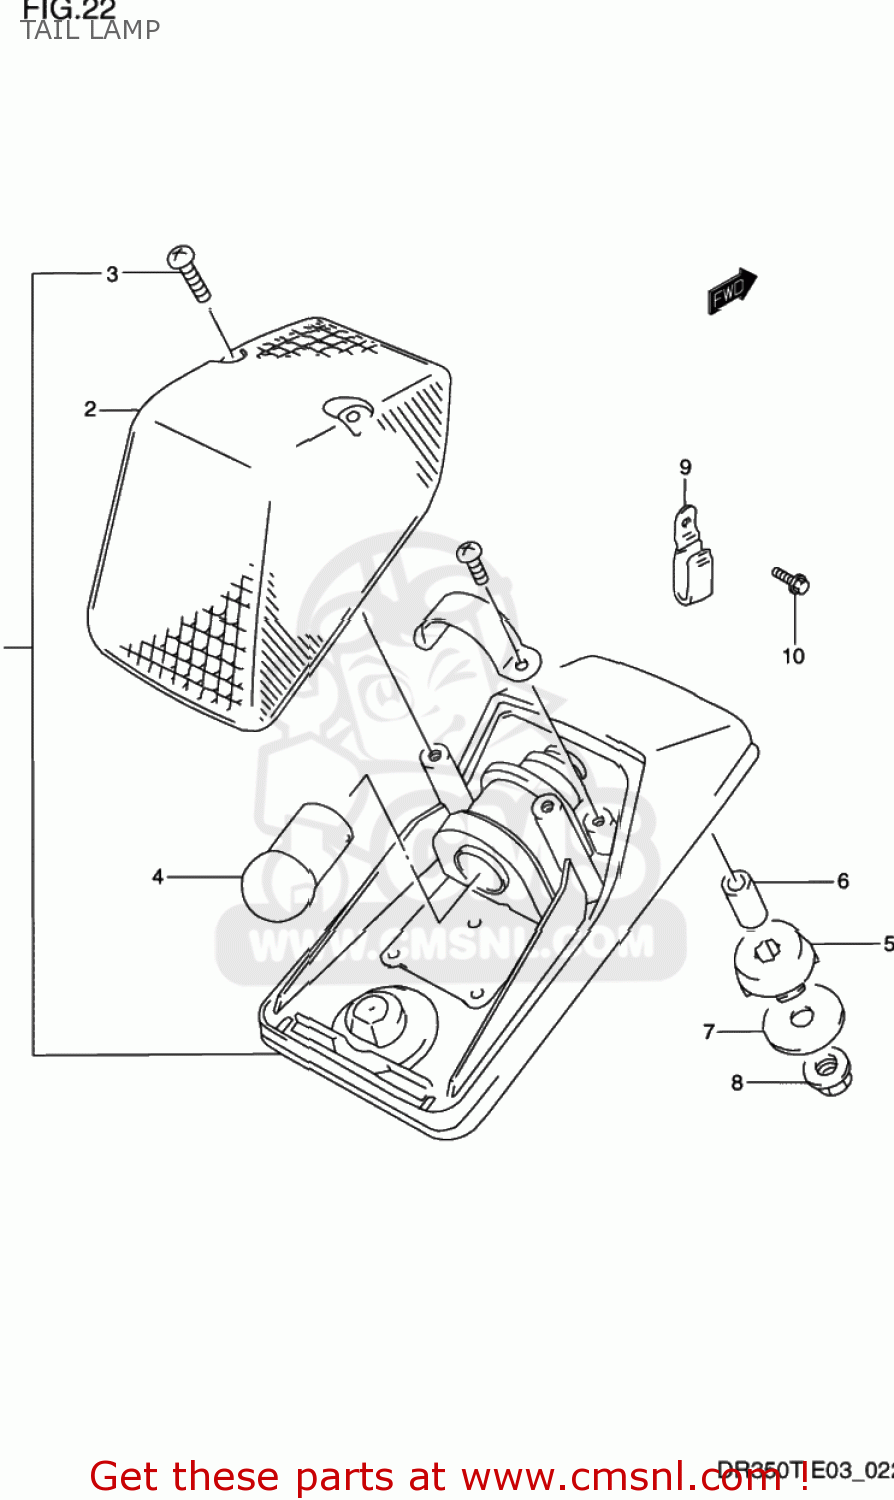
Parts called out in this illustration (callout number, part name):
1	LAMP ASSY,TAIL
2	LENS
3	SCREW
4	BULB(12V5W,BF150-40160A)
5	CUSHION
6	SPACER(6.4X9.2X12)
7	WASHER
8	NUT
9	CLAMP
10	SCREW
